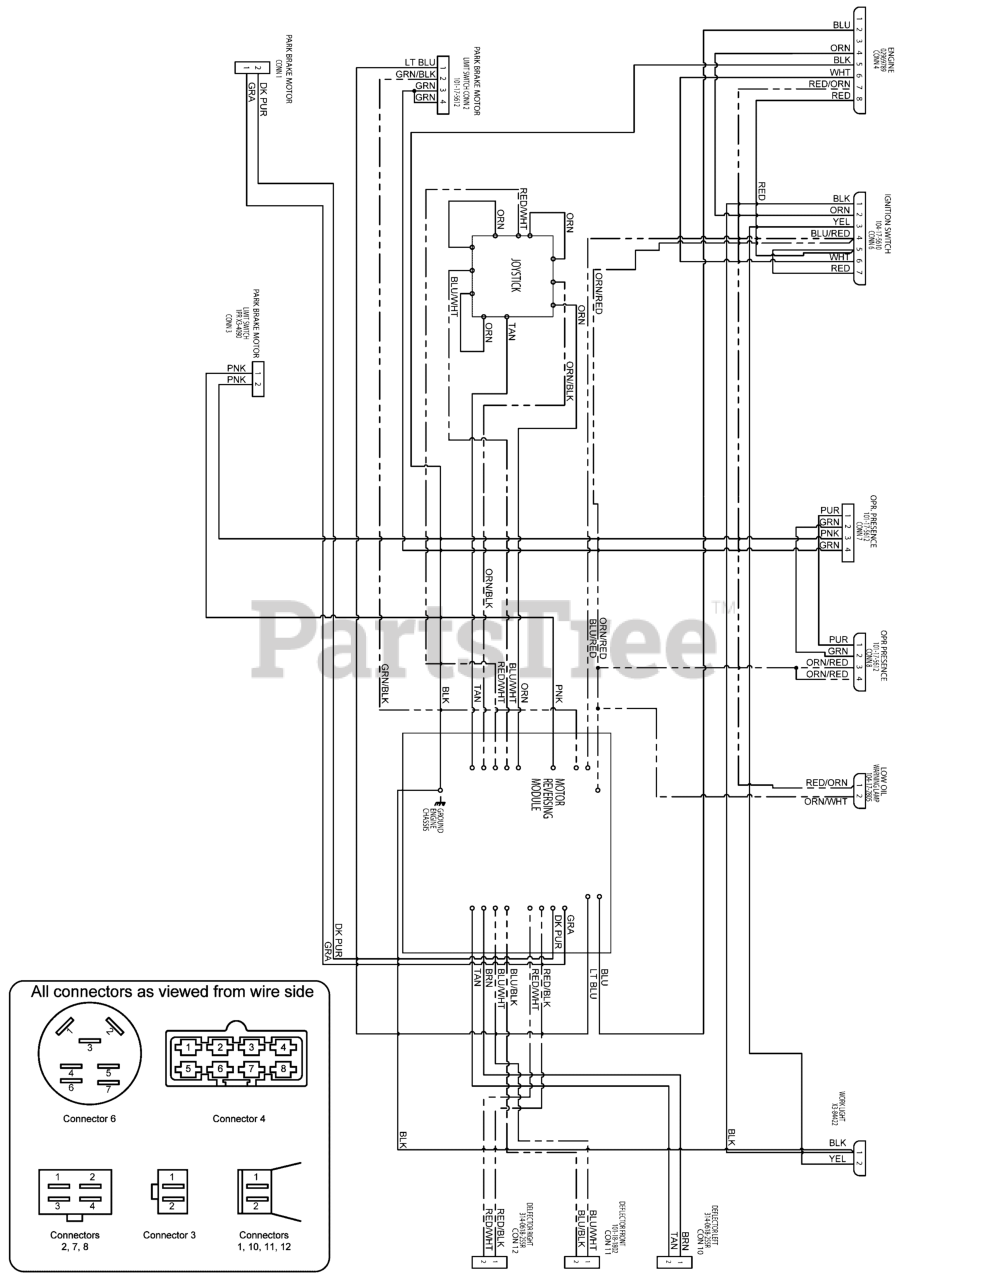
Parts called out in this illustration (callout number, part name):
1	HARNESS, WIRING
2	HARNESS, WIRING
3	HARNESS, WIRING
